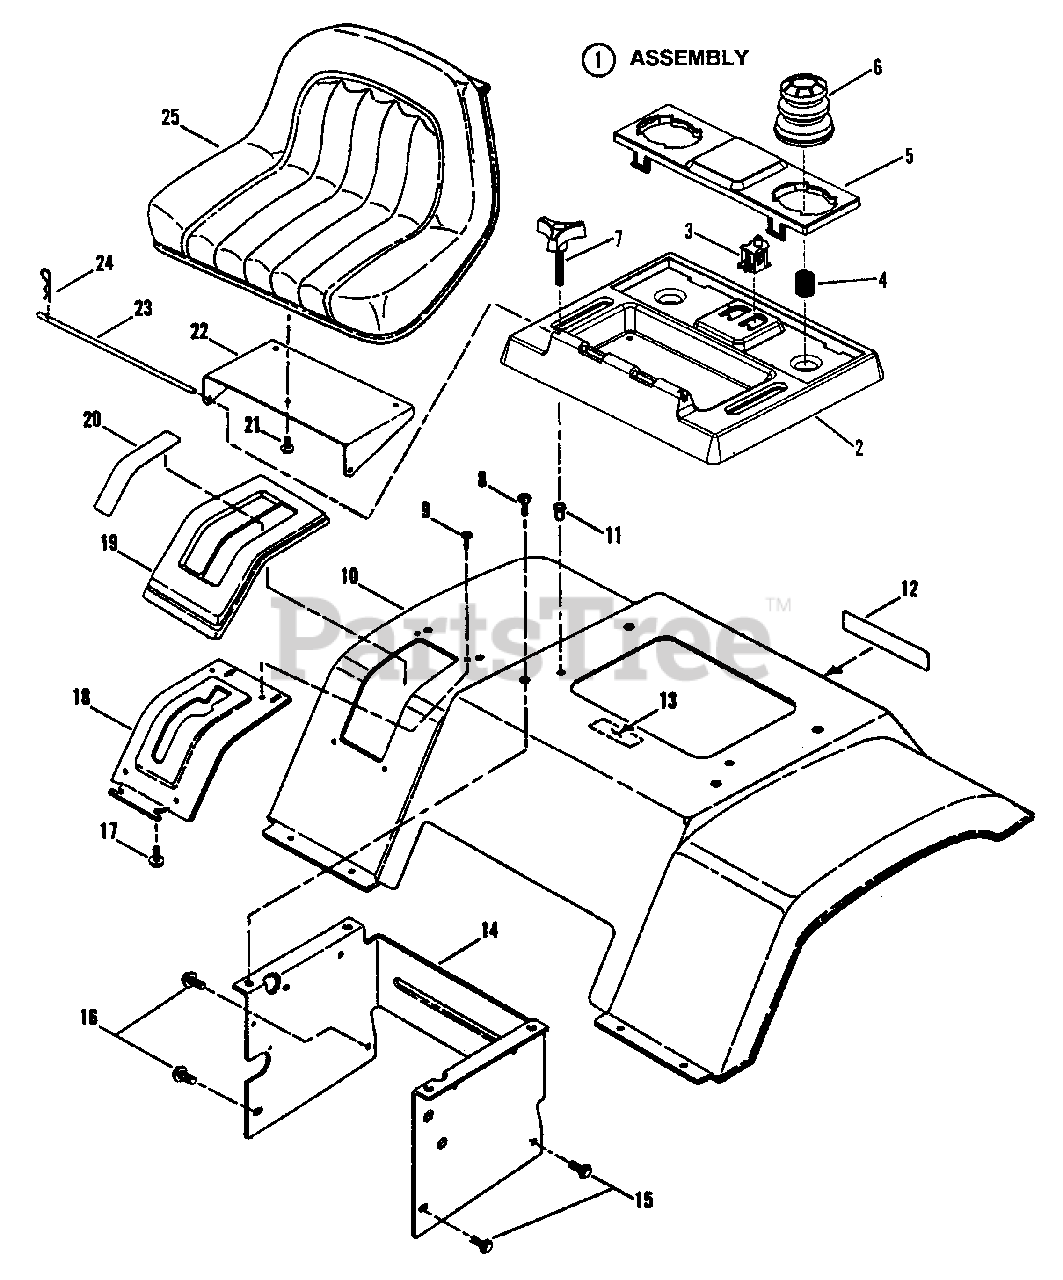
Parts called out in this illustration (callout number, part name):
1	ASSEMBLY, Seat Support
2	SUPPORT, Seat
3	SWITCH, Seat, Gray, NC
4	SPRING
5	HOLDER, Cushion
6	CUSHION, Seat
7	KNOB, Seat Adjustment
8	SCREW, 5/16-18 x 5/8" Truss Head, Torx
9	SCREW, 1/4-20 x 5/8" Hex Washer Head, Self-Tapping
10	PAN, Seat (Fender)
11	RIV-NUT, 5/16-18 Round
12	DECAL - SNAPPER, 7.28" Molded Logo, Silver Letters & Blue Stripe
13	DECAL - CAUTION, Battery Location
14	SUPPORT, Fender
15	SCREW, 5/16-18 x 5/8" Hex Washer Head, Swage Form
16	SCREW, 5/16-18 x 1-1/4" Hex Washer Head, Swage Form
17	SCREW, #10-16 x 1/2" Hex Washer Head, Self-Tapping
18	DETENT, Shift
19	COVER, Shift
20	DECAL, Shift Cover, 5-Speed
21	BOLT, 5/16-18 x 1/2" Hex Flange Lock, Grade 5
22	BRACKET, Seat Support
23	ROD, Seat Hinge
24	PIN, 3/32 x 1-1/2" Hair
25	SEAT, Operator's
